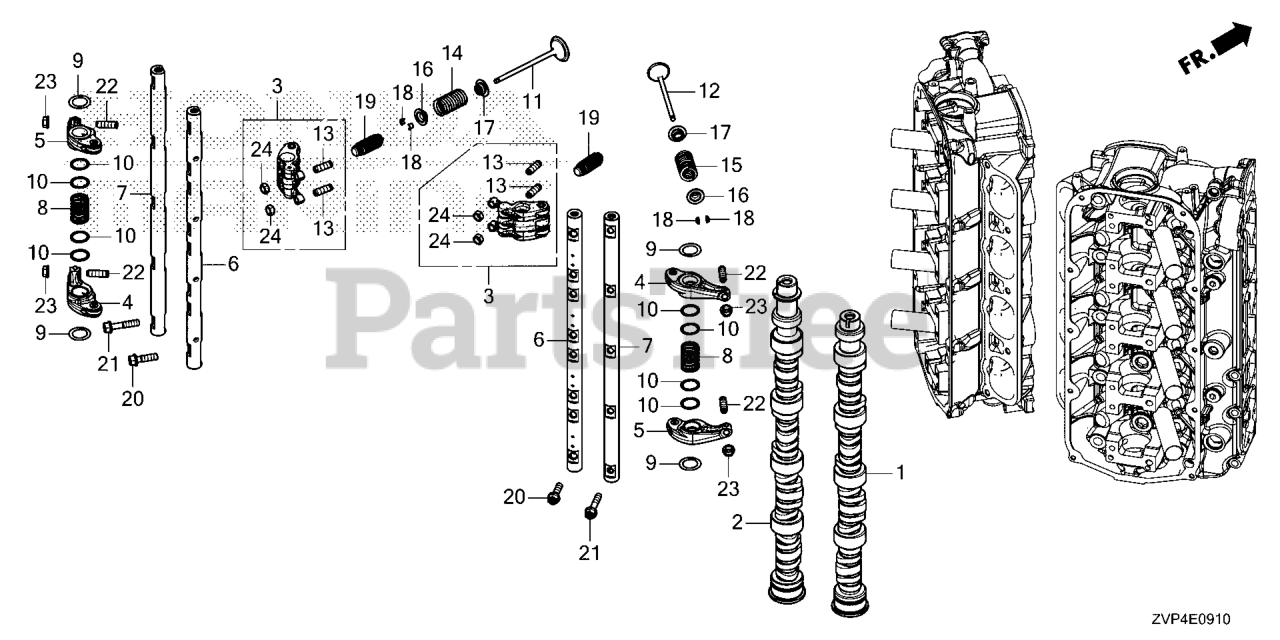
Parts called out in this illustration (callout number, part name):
1	CAMSHAFT, R
2	CAMSHAFT, L
3	ARM ASSY., IN. ROCKER
6	SHAFT COMP
7	SHAFT COMP
8	SPG, RKR ARM
9	WASHER, THRUST
10	WASHER (25MM)
11	VALVE, IN.
12	VALVE, EX.
13	SCREW, TAPPET ADJUSTING
14	SPRING, VALVE (PINK) (NIPPON HATSUJO)
15	SPRING, EX. VALVE (YEL/GRN) (ASSOCIATE)
16	RETAINER, VALVE SPRING
17	SEAT, VALVE SPRING
18	COTTER, VALVE (FUJI VALVE)
19	MOTION, LOST
20	BOLT, FLANGE (8X30)
21	BOLT, FLANGE (8X40)
22	SCREW, TAPPET ADJG
23	NUT, TAPPET ADJUSTING (TOKAI TRW)
24	NUT, TAPPET ADJUSTING
